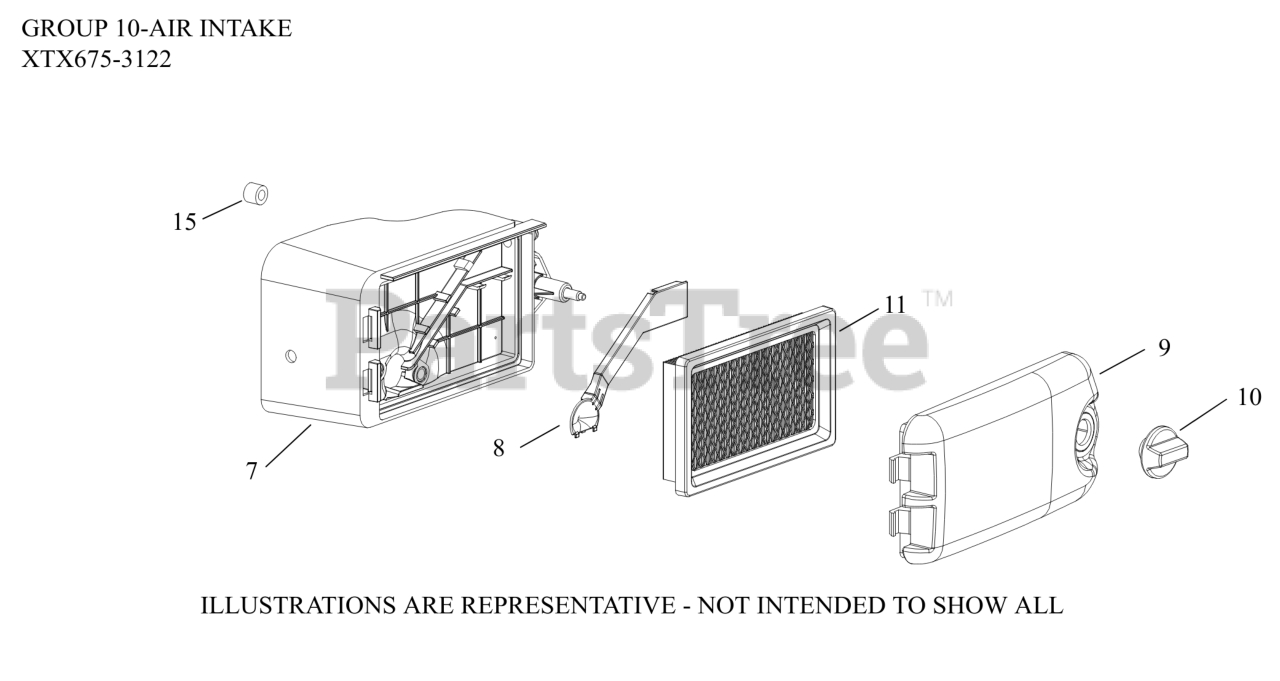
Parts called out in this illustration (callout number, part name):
7	AIR CLEANER BASE-USE 14 094 23-S
8	COVER, A/C BASE (BREATHER GAS)
9	COVER, AIR CLEANER
10	KNOB-USE 14 341 07-S
11	ELEMENT, AIR FILTER
15	SPACER, AIR CLEANER BASE
